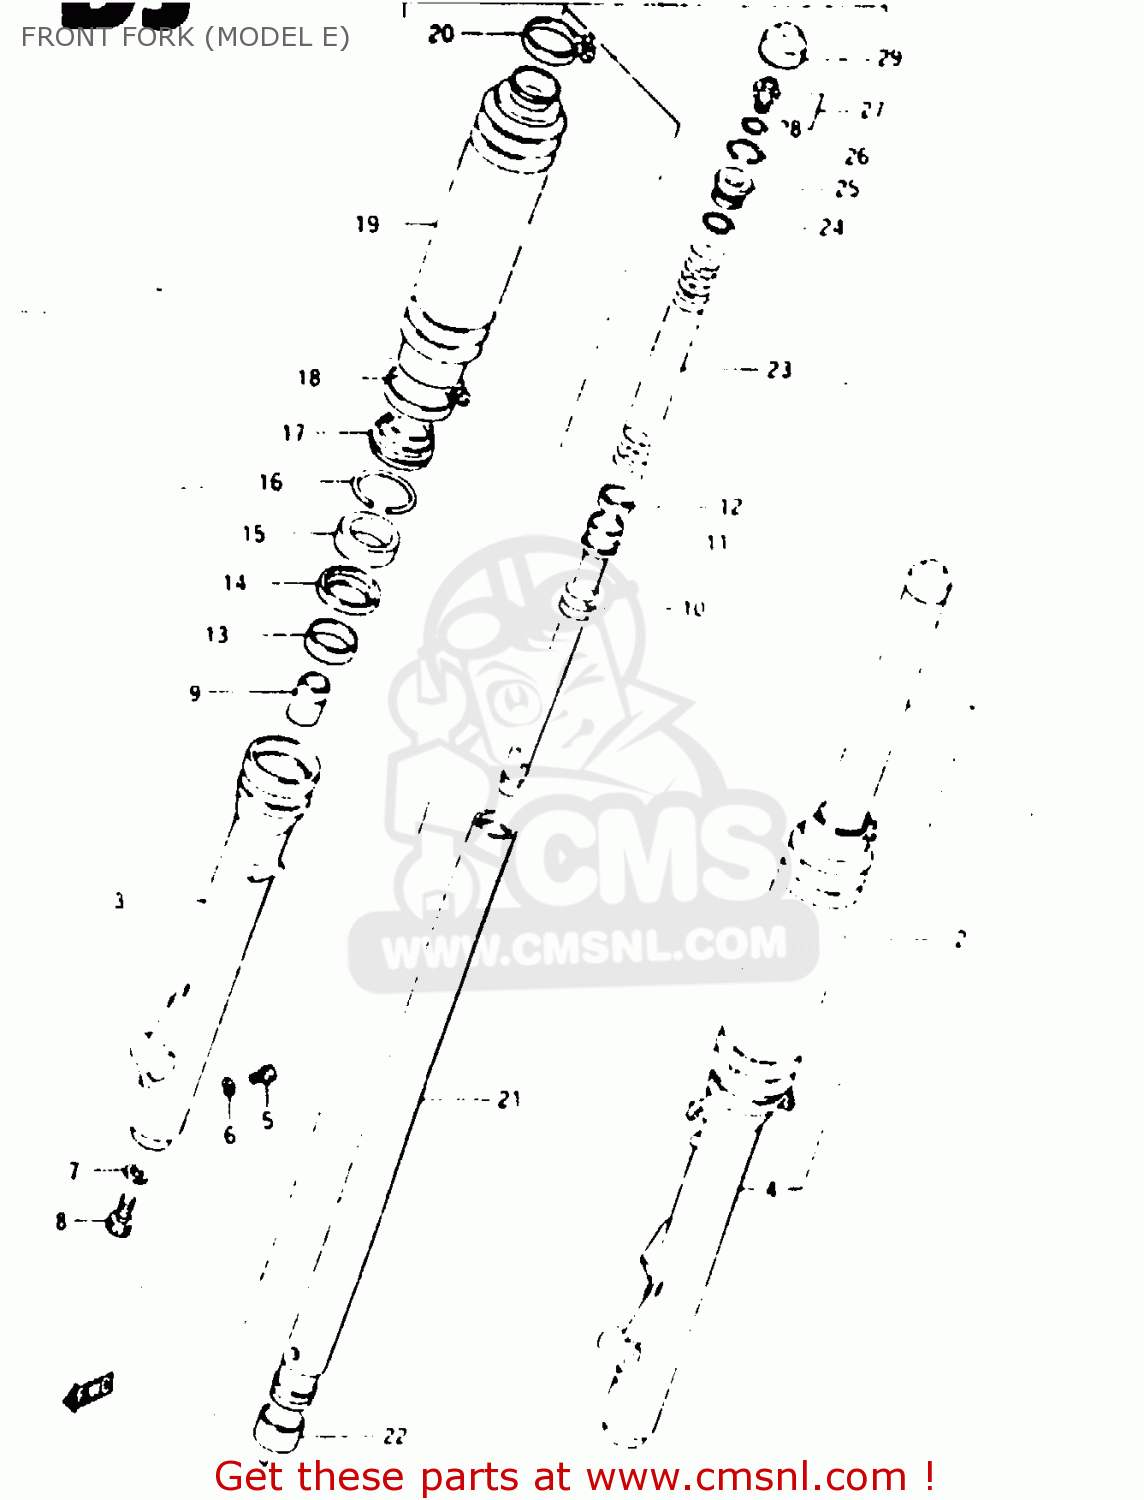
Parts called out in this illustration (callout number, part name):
1	DAMPER ASSY, RH (BLUE)
2	DAMPER ASSY, LH (BLUE)
3	OUTER TUBE, RH
4	OUTER TUBE, LH
5	BOLT(6X8)
6	GASKET,DRAIN,PLUG (NAS)
7	GASKET (NAS)
8	BOLT(8X27)
9	PIECE,OIL LOCK
10	SPRING,REBOUND
11	CYLINDER
12	RING,PISTON
13	BUSH,GUIDE
14	SPACER,SEAL
15	OIL SEAL
16	RING,OIL SEAL STOPPER
17	SEAL,DUST
18	BAND
19	BOOT
20	BAND
21	TUBE,FORK,INNER
22	PISTON
23	SPRING
24	O RING
25	SEAT,SPRING
26	RING,STOPPER
27	VALVE,AIR
28	O-RING (D:3.8 ID:19)
29	CAP
